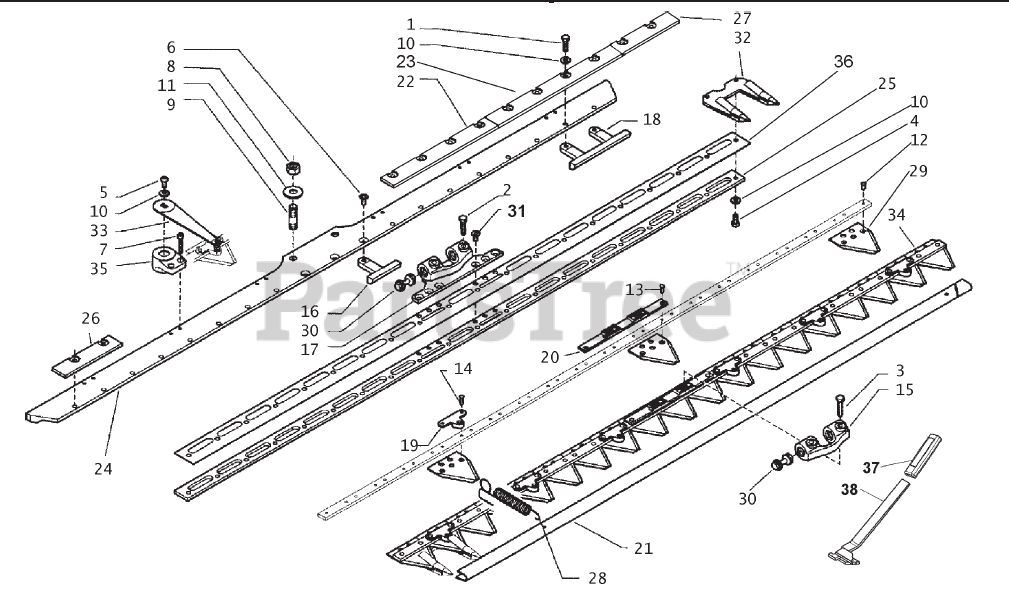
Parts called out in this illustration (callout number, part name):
1	CAPSCREW, M8X20
2	CAPSCREW, M8X30
3	CAPSCREW, M8X35
4	CAPSCREW, M8X1X15
5	SCREW, M8X16
6	SCREW, M8X16
7	SCREW, M8X20
8	NUT, M14X1 5.6S
9	STUD, M14X1.5X48X12X20
10	WASHER, SUPER, M8
11	WASHER, SUPER, M14
12	RIVET, 5.3X12
13	RIVET, 5.3X14
14	RIVET, 5.3X16
15	STEEL BLADE COUPLING
16	GUIDE LOWER
17	COUPLER XL COMB
18	GUIDE LOWER
19	COUPLER BLADE HOLDER
20	KNIFE PLATE
21A	GUARD, BLADE 47"
21B	GUARD, BLADE 59"
21C	GUARD, BLADE 71"
22	LOW BLADE GUIDE INTERNAL
23	LOW BLADE GUIDE INT. 59 & 71"
24A	ROD CENTER 47"
24B	ROD CENTER 59"
24C	ROD CENTER 71"
26A	BLADE GUIDE 47"
26B	BLADE GUIDE 71"
27A	BLADE GUIDE 47"
27B	BLADE GUIDE 71"
29	KNIFE SECTION XL THICK
30	SCREW BLADE COUPLING
31	SCREW M8X1X14
32	FINGER COMPLETE
33	SPRING COMPLETE
34A	BLADE COMPLETE 47"
34B	BLADE COMPLETE 59"
34C	BLADE COMPLETE 71"
35	KNIFE GUIDE SUPPORT ASSEMBL
